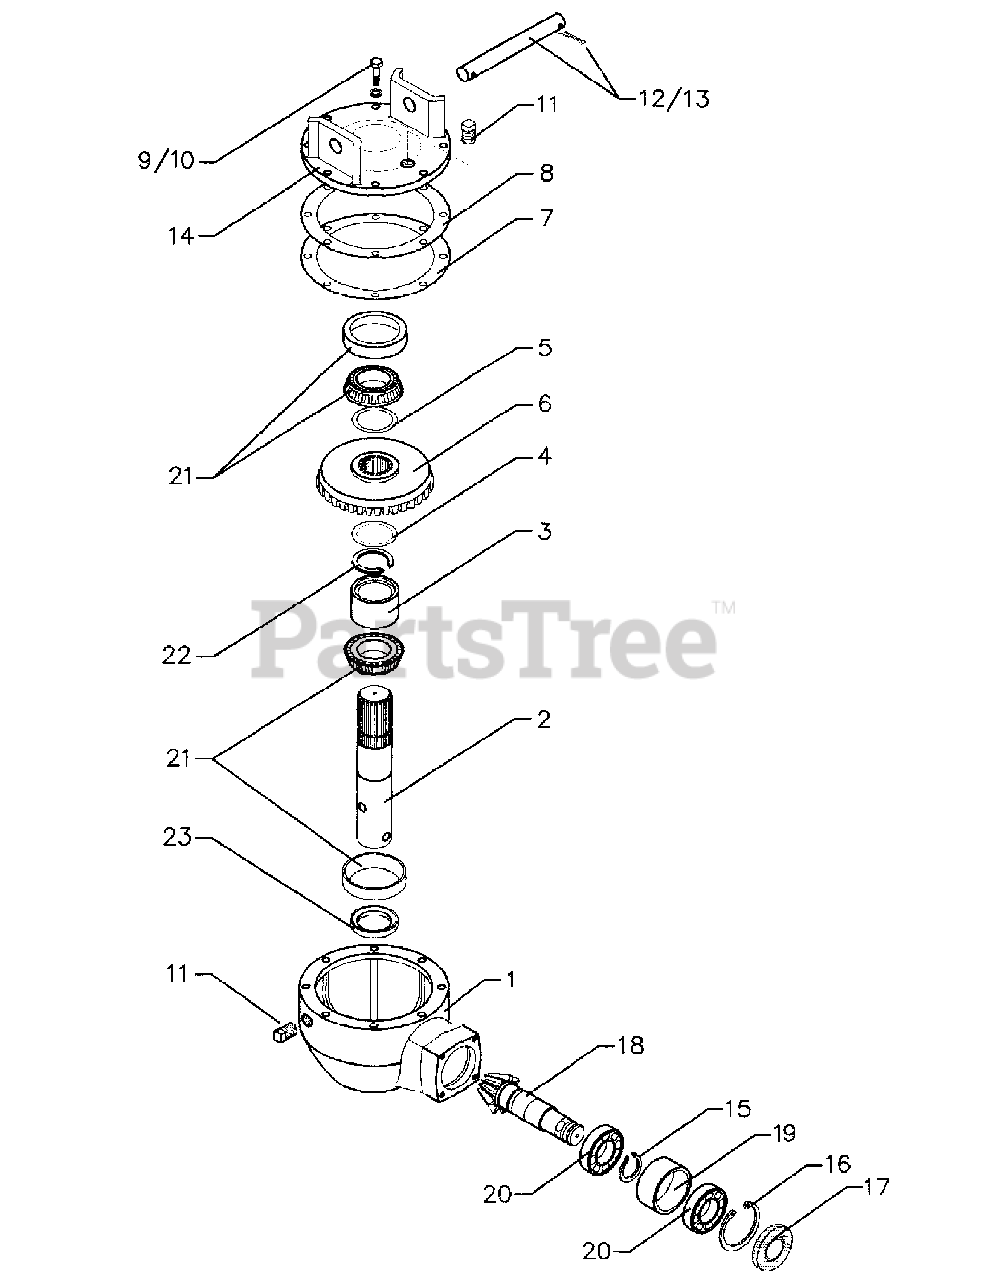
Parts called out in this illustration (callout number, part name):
1	Housing PHD200
2	Output shaft PHD200
3	Output bearing spacer PHD200
4	Gear adjusting shim (0.30)
5	Gear adjusting shim (0.50)
6	Output gear (33 teeth) PHD200
7	Output cap gasket (0.10) PHD200
8	Output cap gasket (0.25) PHD200
9	Lock washer Ø10
10	Bolt M10x30
11	Pipe plug ½"
12	Hanger shaft
13	Cotter pin
14	Hanger cap PHD200
15	Retaining ring
16	Retaining ring
17	Oil seal 35-72-10
18	Pinion gear and shaft (11 teeth) PHD200
19	Bearing spacer
20	Bearing 6207
21	Bearing 30210
22	Retaining ring
23	Output seal 50x70x12
